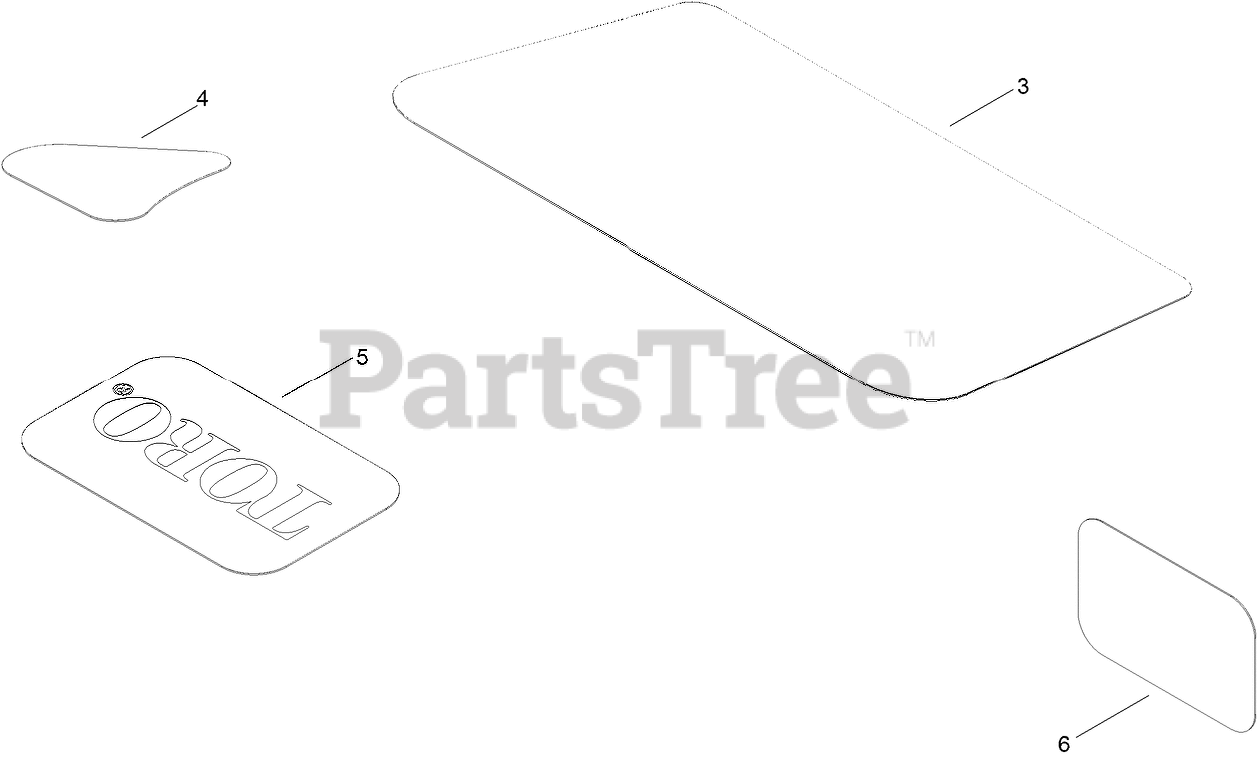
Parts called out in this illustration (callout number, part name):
3	DECAL-ENGINE
4	DECAL-DRAIN, OIL
6	PLACARD-INTAKE
